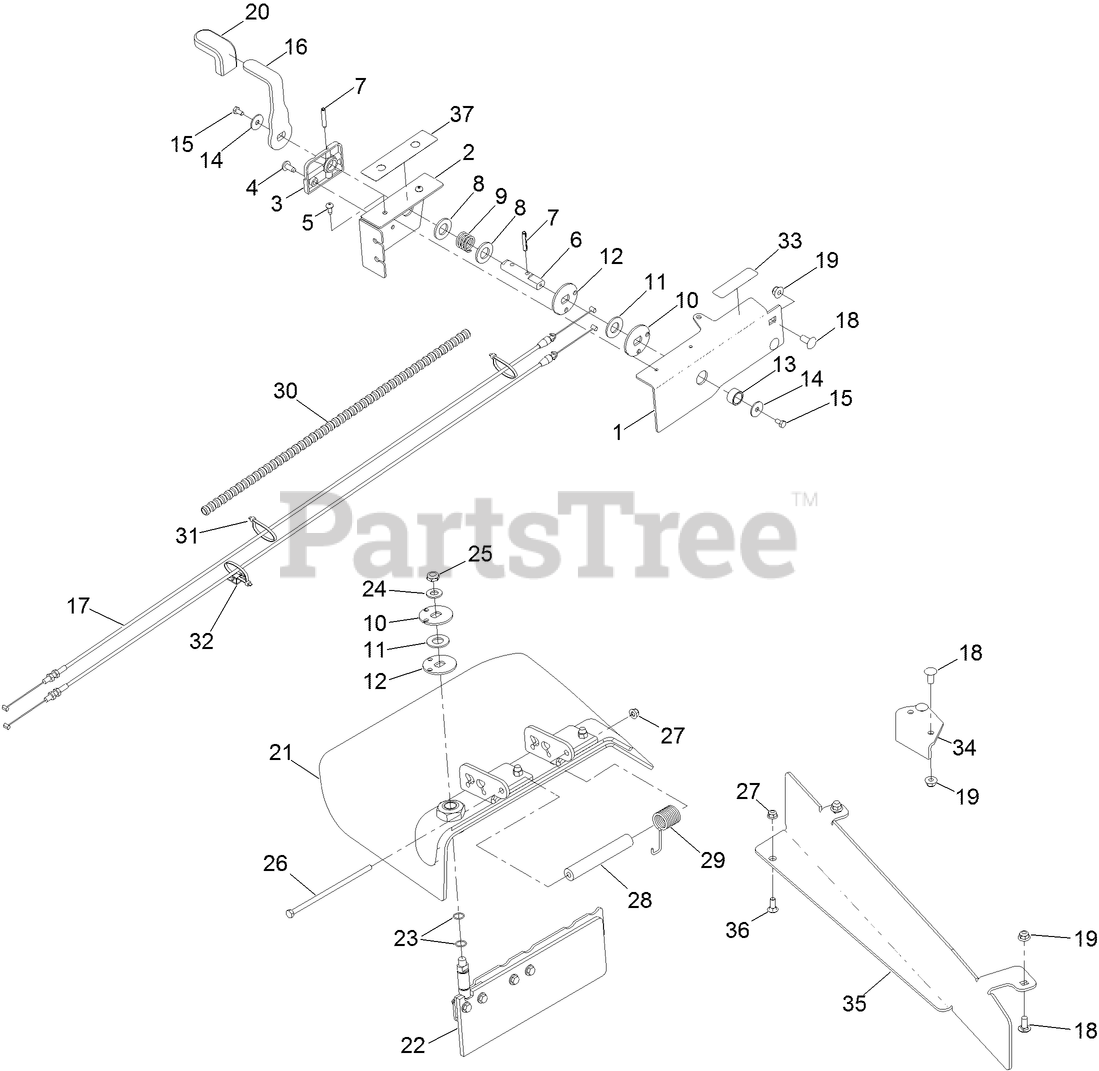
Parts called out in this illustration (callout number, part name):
1	BRACKET-MOUNTING, OCDC
2	BRACKET-COVER
3	BLOCK-DETENT
5	SCREW-TPH THD FORM
6	PIN-PIVOT
7	PIN-ROLL
8	WASHER-FLAT
9	SPRING-COMPRESSION
10	PULLEY-TOP
11	PULLEY-MIDDLE
12	PULLEY-BOTTOM
13	BUSHING
14	WASHER-FLAT
15	SCREW-HH
16	HANDLE-PIVOT
18	SCREW-CARR
19	NUT-HF, NI
20	GRIP-LEVER
21	RUBBER DEFLECTOR ASM
22	ASM-DOOR
23	O-RING
24	WASHER-FLAT
25	NUT-HEX
26	SCREW-HH
27	NUT-HF, NI
28	SPACER
29	SPRING-TORSION
30	TUBE-CONVOLUTED
31	TIE-CABLE
32	MOUNT-TIE, CABLE
33	DECAL-CONTROL, MOTION
34	BAFFLE-DISCHARGE
35	BAFFLE-BAGGER
36	SCREW-CARR
37	DECAL-CHUTE GATE
